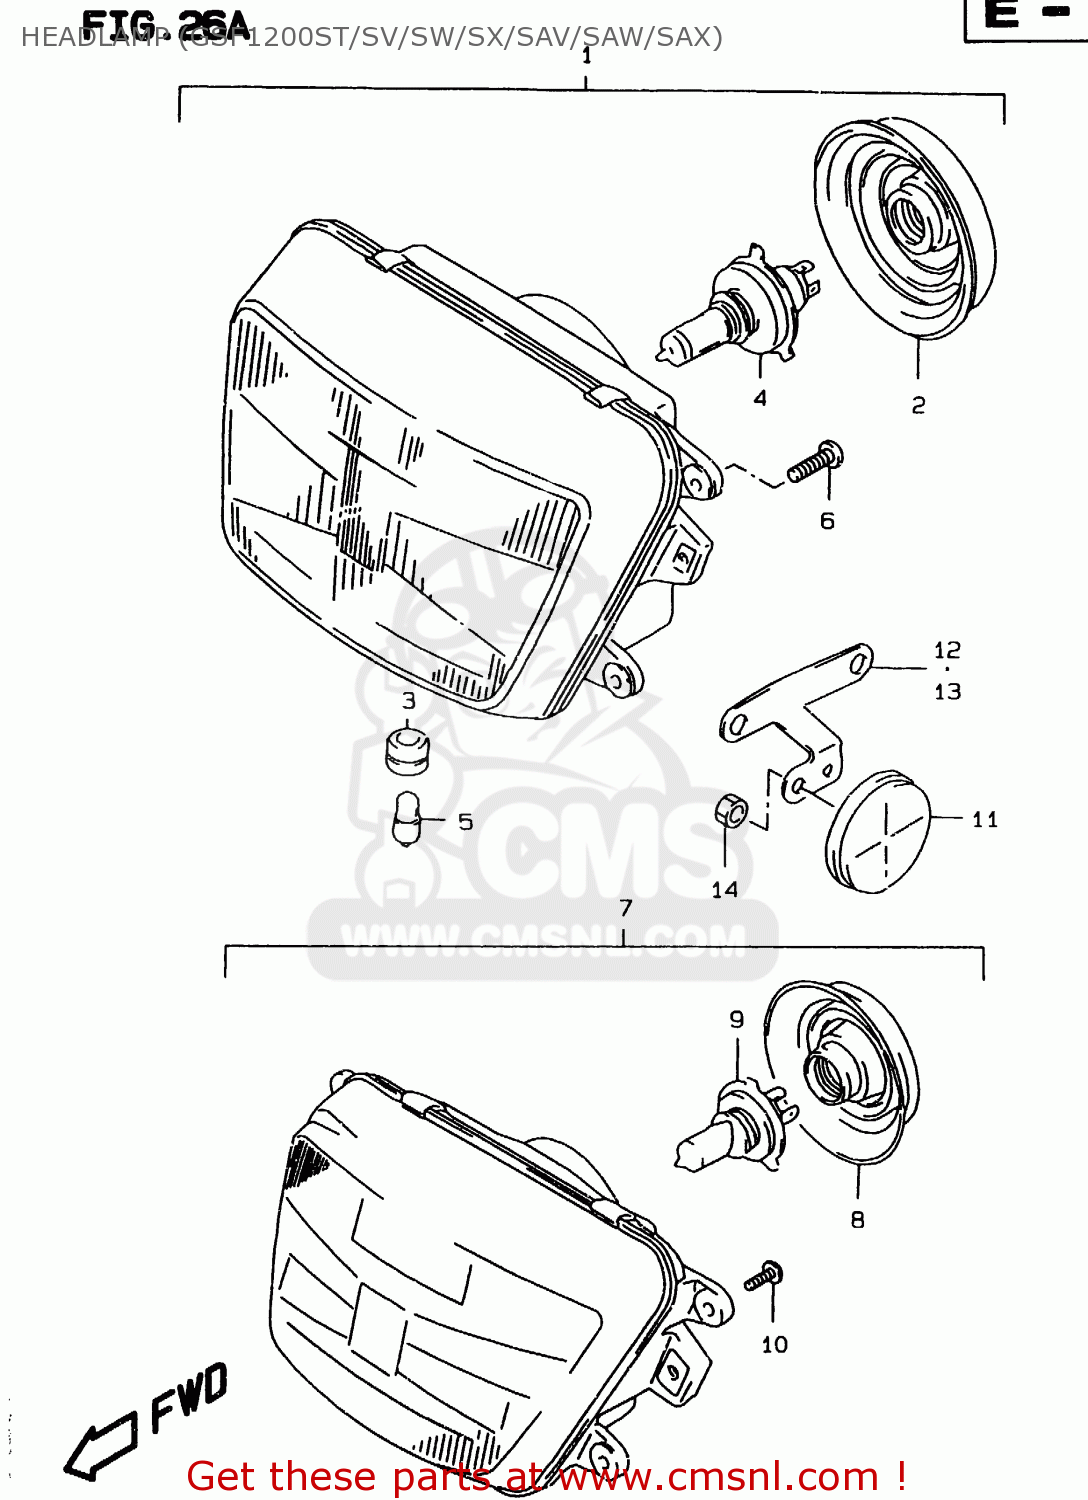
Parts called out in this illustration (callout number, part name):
1	HEADLAMP ASSY
2	COVER,SOCKET
3	JOINT,RUBBER
4	BULB(12V60/55W,H4)
5	BULB(12V4W)
6	SCREW
7	HEADLAMP ASSY
8	COVER,SOCKET
9	BULB(12V60/55W,H4)
10	SCREW
11	REFLECTOR,REFLEX FR
12	BRACKET,FR SIDE REFLECTOR,R
13	BRACKET,FR SIDE REFLECTOR,L
14	NUT
